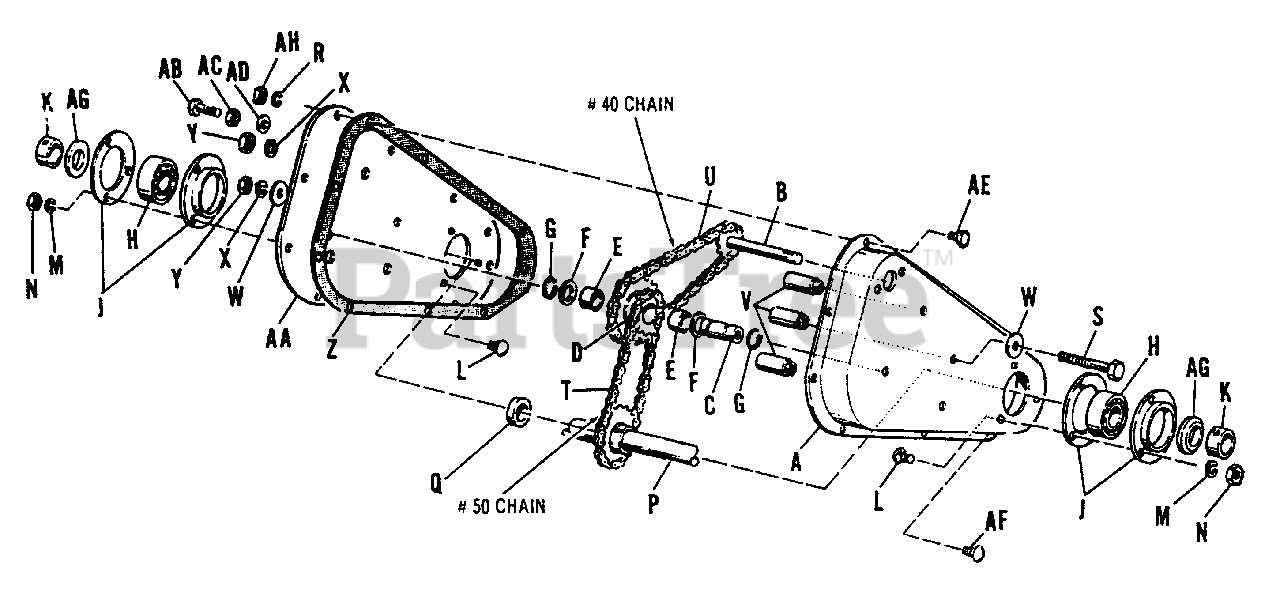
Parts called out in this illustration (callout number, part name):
A	Guard Assembly Chain
B	Shaft Assembly Drive
C	Spacer, Intermediate
D	Sprocket Assembly
E	Bearing, Roller
G	Ring, Retaining
J	Flange, Bearing
K	Collar, Bearing
L	Bolt Carriage, 3/8"-16 NC x 3/4" lg.
M	Washer Lock 3/8"
N	Nut, Hex. Full 3/8"-16 NC
P	Tine Shaft Assembly
R	Washer, Lock 5/16"
S	Capscrew Hex 7/16"-14 NC x 3-3/4" lg.
T	Chain, Rotor
U	Chain, Drive
V	Spacer, Guard
X	Washer, Lock 7/16"
Y	Nut, Hex, Full 7/16"-14 NC
AA	Plate Assembly
AB	Capscrew, Hex, 3/8"-24 NF x 2-1/2" lg.
AC	Nut, Hex. Jam, 3/8"-24 NF
AD	Washer Plain 3/8"
AE	Capscrew, Hex, 5/16"-18 NC x 5/8" lg.
AF	Carriage, Bolt 5/16"-18 NC x 3/4" lg.
AH	Nut, Hex, Full 5/16"-18 NC
